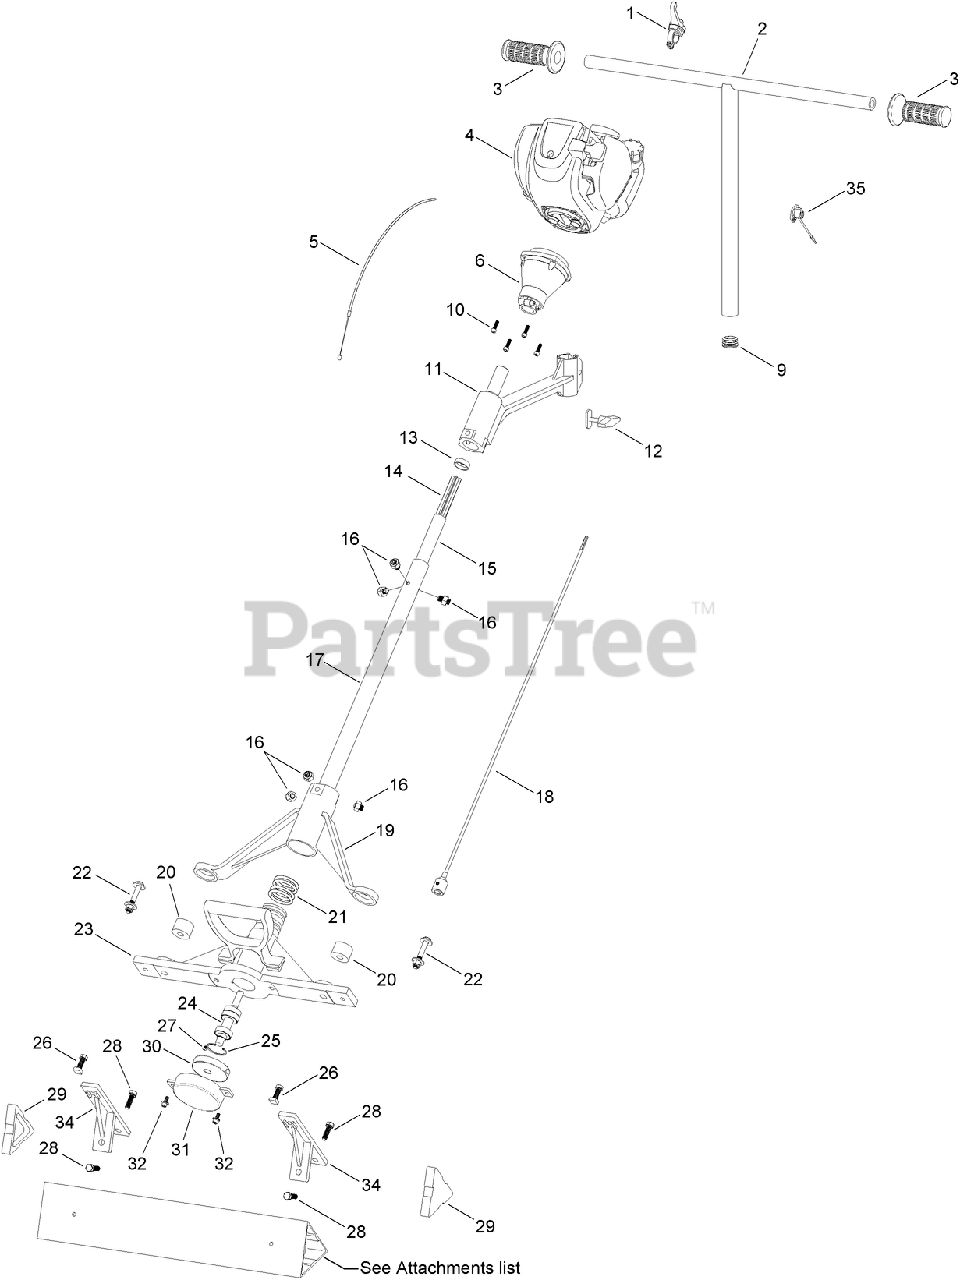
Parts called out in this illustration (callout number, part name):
1	THROTTLE LEVER ASM
2	T-BAR ASM
3	GRIP-T BAR
4	ENGINE-HONDA
5	CABLE-THROTTLE
6	CLUTCH
9	PLUG-CAP, T-BAR
10	SCREW-HH
11	MOUNT-UPPER, HEAVY DUTY
12	KNOB ASM
13	BUSHING-TUBE, OUTER
14	LINER-STAR
15	LINER-TUBE, ALUMINUM
16	SET SCREW ASM (W/JAM NUTS)
17	TUBE-OUTER, STAINLESS
18	SHAFT-DRIVE, FLEX
19	LOWER CASTING ASM #2
20	SHOCK ABSORBER
21	O-RING
22	SHOCK BOLT KIT
23	LOWER CASTING ASM #1
24	SHORT SHAFT ASM (W/BEARINGS)
25	RING-SNAP, LARGE
26	BAR BOLT ASM (SADDLE CLAMP)
29	CAP-END, BAR
30	WEIGHT-ECCENTRIC (W/SETSCREW)
31	CAP-END
32	END COVER BOLT KIT
34	CLAMP-SADDLE
35	KILL SWITCH ASM
